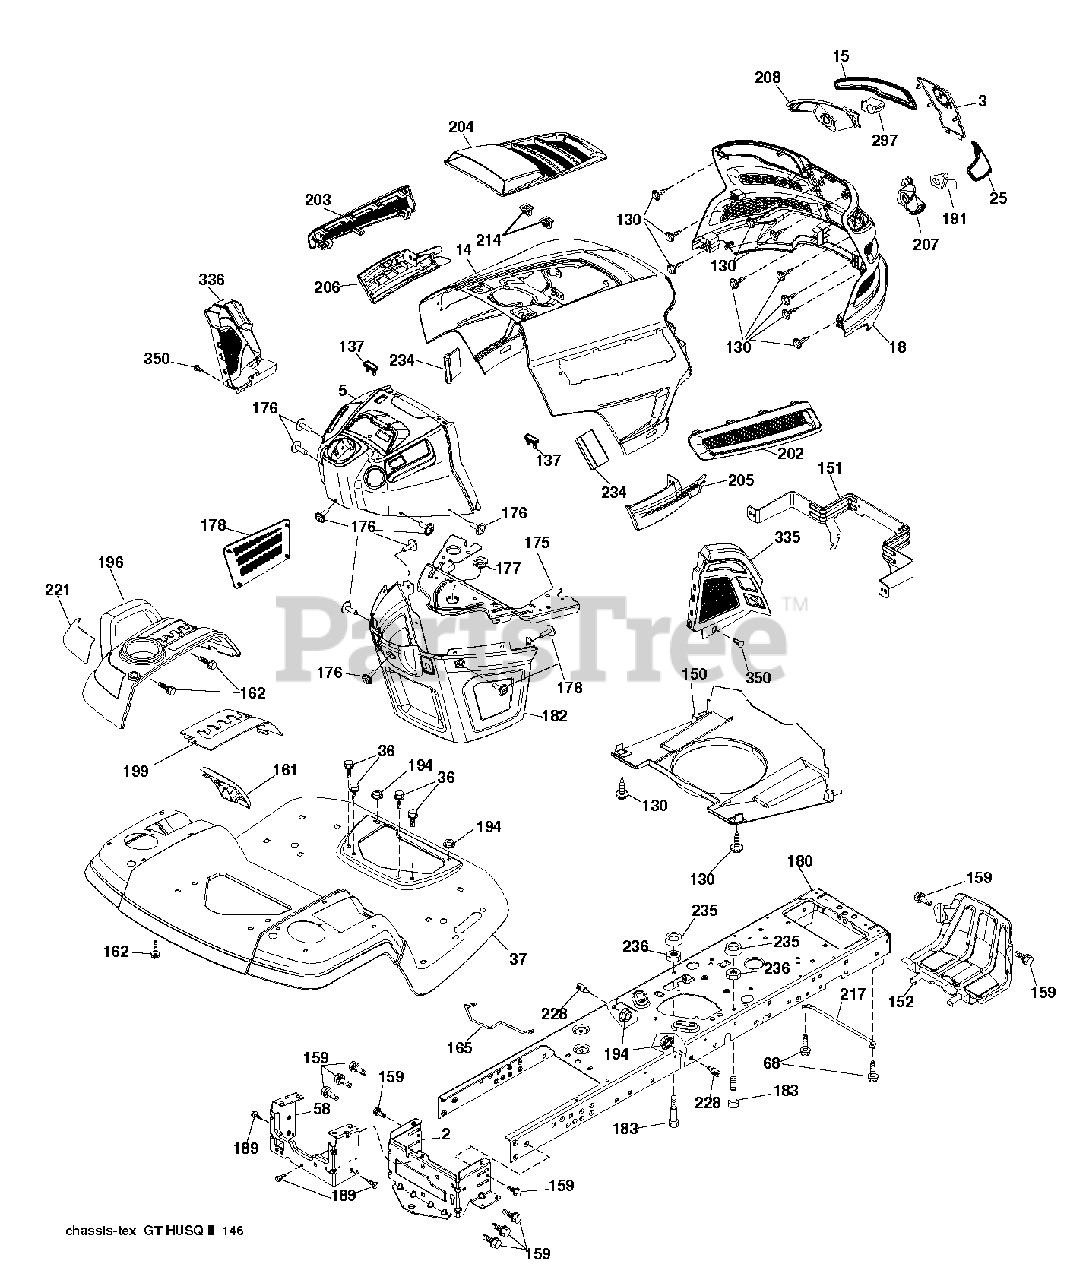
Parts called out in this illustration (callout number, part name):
2	DRAWBAR.LOWER.2PC.18/22
3	APPLIQUE.SUBASM.GT.HUSQ.II
5	DASH.HUSQ2.SM.E.NC.HR.CHG.498
14	HOOD.ASM.HUSQVARNA.GT.TEX.ORAN
15	LENS.HEADLIGHT.LH.GTII.2011
18	GRILLE.SUBASM.GT.HUSQ.II
25	LENS.HEADLIGHT.RH.GTII.2011
36	SCREW 5/16"
37	FENDER.PNT.TX.GT.CH/FW/DL.HUSQ
58	DRAWBAR.UPPER.2PC,LRG.FENDER
68	SCREW LT
130	SCREW.#10 X 0.750.BOS
137	BUMPER DASH
150	AIR.DUCT.GTV.BLACK
151	BRACKET.PIVOT.HOOD.GT.HUSQ.II
152	SHIELD.BROWNING.PNT.GT.V2
159	SCREW, 3/8-16X3/4
161	CONSOLE.FUEL.WINDOW.HU
162	SCREW.HI-LO.CONSOLE
165	SUPPORT.TANK.REAR.B/TE
175	PLATE.CROSSMEMBER.HUSQ
176	SCREW.#10-24X5/8.RN.QU
177	BUSHING, STEERING
178	CARGO.ASM.NET.TXGT.W/C
180	CHASSIS.TEX.BOLTED
182	DASH.LOWER.COMMON.12V.ADAPTOR
183	BOLT.5/16-18X1-1/4 FULL THD
189	SCREW
191	INSERT.REFLECTIVE.RH.HUSQ.GTII
194	NUT LOCK HEX FLANGE 5/16-18
196	CONSOLE.ASM.DECKLIFT.HUSQGT.DL
199	PLATE.DECK.LIFT.HUSQVARNA.GT
202	VENT.SIDE.RH.GT.HUSQ.II.
203	VENT.SIDE.LH.GT.HUSQ.II.498
204	VENT.TOP.HUSQ.GT2
205	SIDE.TRIM.RH.GT.HUSQ.II
206	SIDE.TRIM.LH.GT.HUSQ.II.GRAY
207	BEZEL LIGHT.RH.GT.II.MYLAR
208	BEZEL LIGHT.LH.GT.II.MYLAR
214	CLIP.RETAINER.TINNER.
217	ROD.PIVOT.HOOD
221	REFLECTOR.LH.TEX GT HU
228	STUD.FASTNER.W/ANTI-ROTATE
234	BUMPER.HOOD.TEX.HUSQVARNA
235	SPACER FENDER
236	NUT.CENTERLOCK.5/16-
297	INSERT.REFLECTIVE.LH.HUSQ.GTII
335	COVER.LOWER.DASH.RH.BLACK
336	COVER-LH.LOWER.DASH.GT2.BLACK
350	CLIP.X-MAS.TREE
